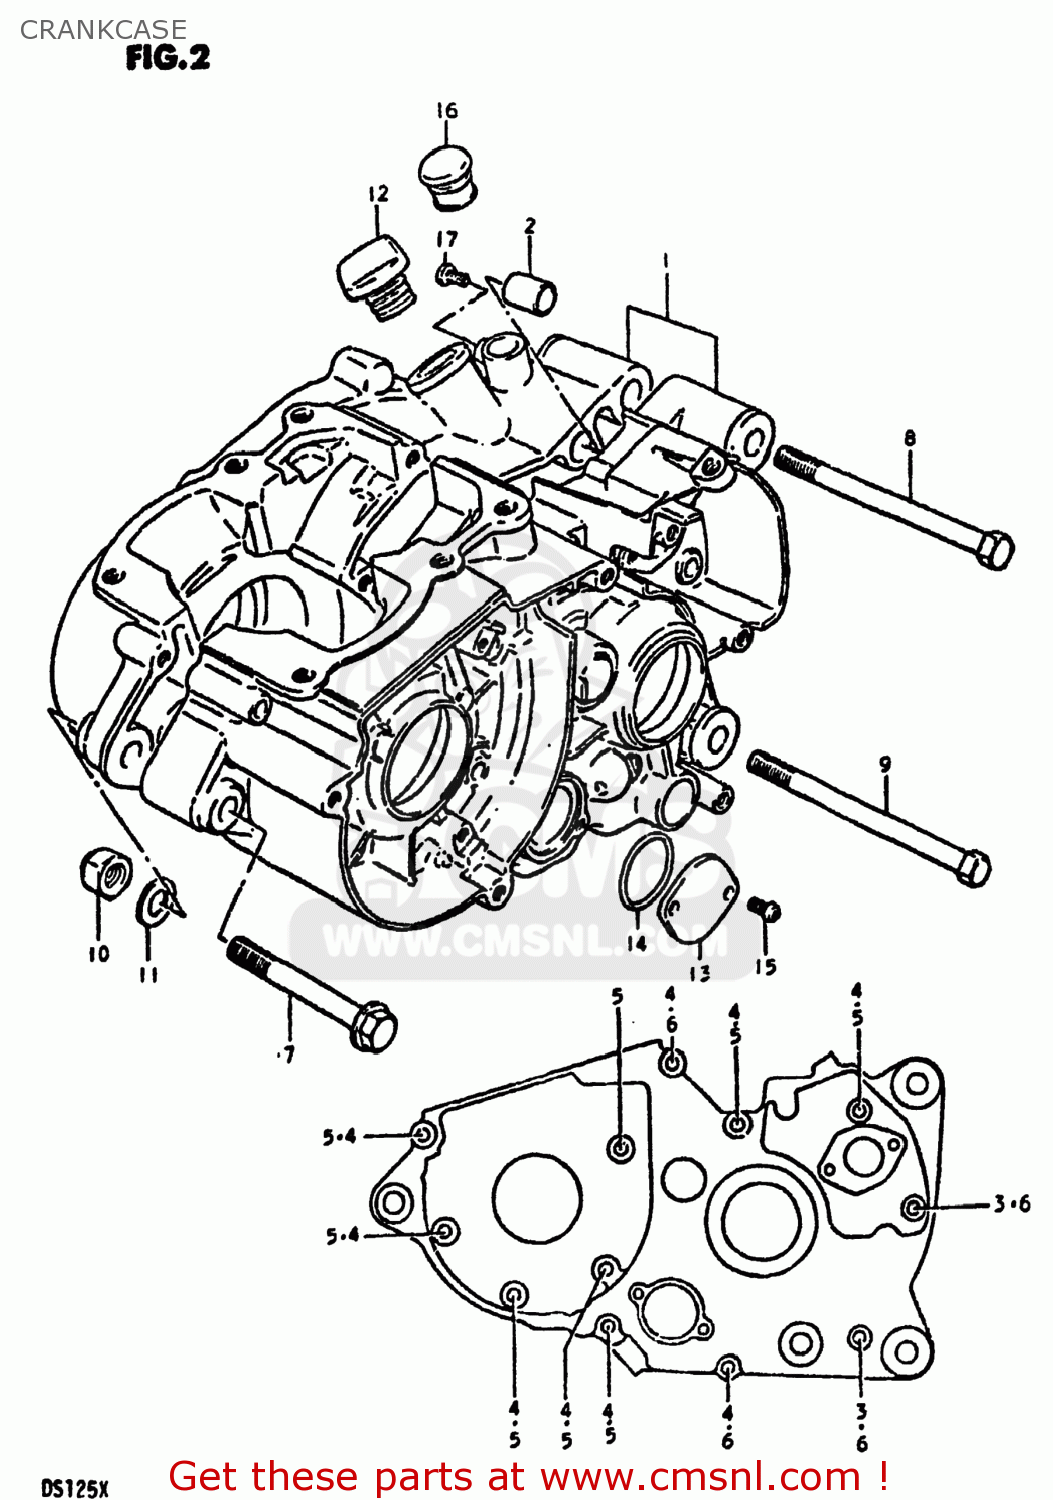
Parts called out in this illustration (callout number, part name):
1	CRANKCASE SET
2	PIN
3	SCREW (6X35)
4	SCREW (6X45)
5	SCREW 6X60
6	SCREW
7	BOLT (10X75)
8	BOLT(10X110)
9	BOLT
10	NUT
11	WASHER
12	PLUG
13	CAP,GEAR SHIFT CAM PIVOT
14	O-RING (D:2.4 ID:26.2)
15	SCREW
16	Plug
17	SCREW,6X6
